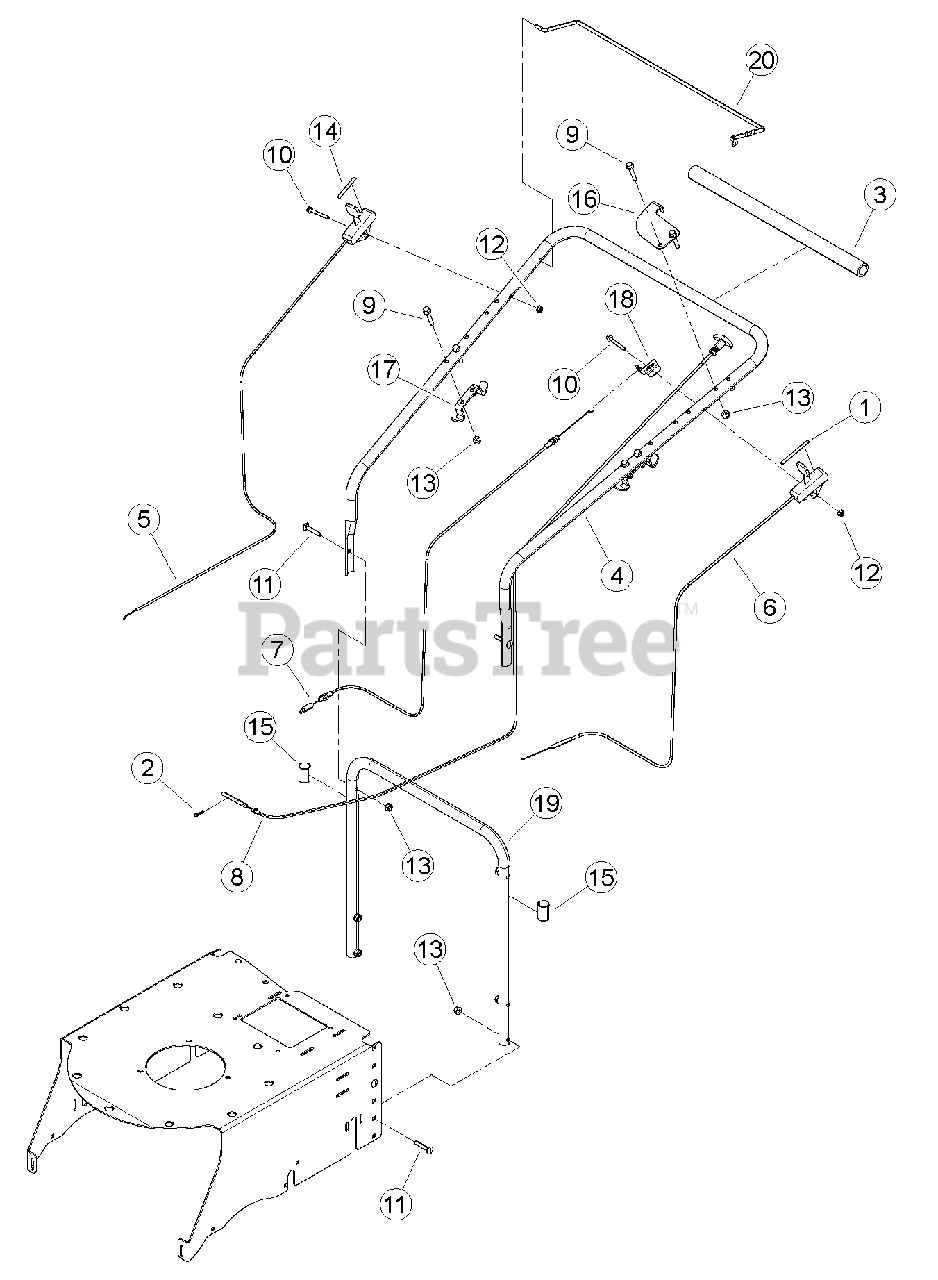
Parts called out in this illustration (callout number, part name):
1	DECAL, 3 SPEED
2	CLIP, HAIRPIN ZP
3	PAD, FOAM HANDLEBAR
4	HANDLE BAR, BEARVAC UPPER
5	CONTROL, THROTTLE
6	CONTROL, TRANSMISSION SHIFT
7	CONTROL, CLUTCH ENGAGEMENT
8	CONTROL, HEIGHT ADJUSTMENT
9	BOLT, 5/16 X 1-3/4 FLANGE NC
10	BOLT, 1/4 X 2 FLANGE NC
11	BOLT, 5/16 X 1-3/4 GR5 CRG ZP
12	NUT, 1/4-20 NYLOCK FLANGE
13	NUT, 5/16-18 NYLOCK FLANGE
14	DECAL, THROTTLE
15	CAP, 7/8" PLASTIC
16	BRACKET, BEARVAC CABLE MOUNT
17	BRACKET, BAG HANGER
18	BRACKET, CLUTCH CABLE
19	HANDLE BAR, LOWER BEARVAC
20	BAIL, BEARVAC CLUTCH CONTROL
